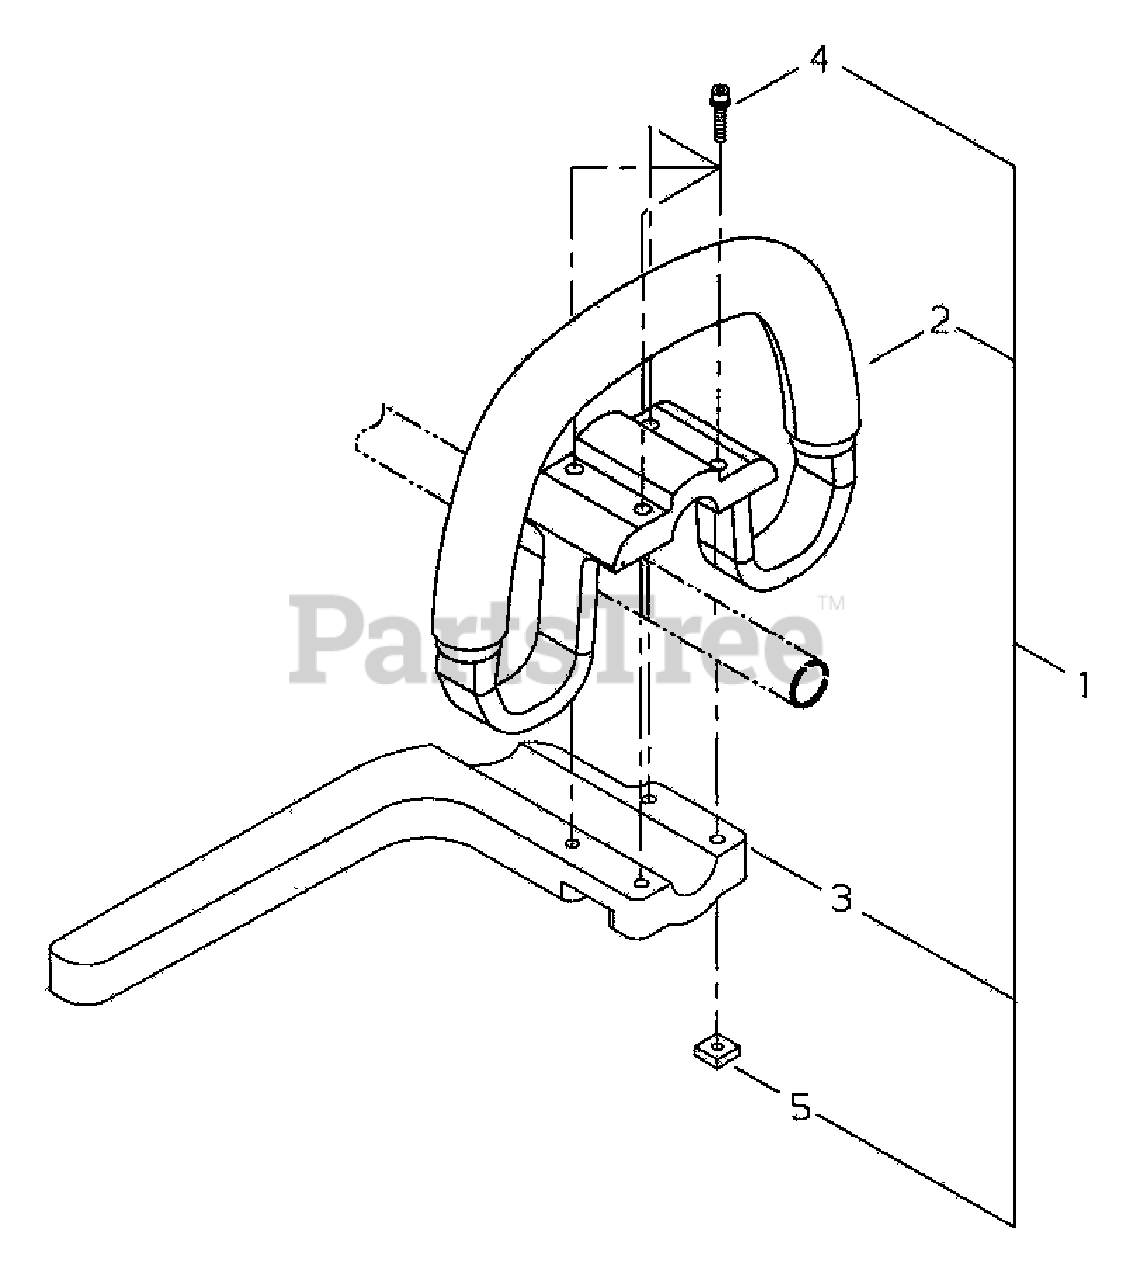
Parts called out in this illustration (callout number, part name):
1	HANDLE ASSY
2	HANDLE
3	BAR, BARRIER
4	SCREW - 5X35
5	NUT - 5
